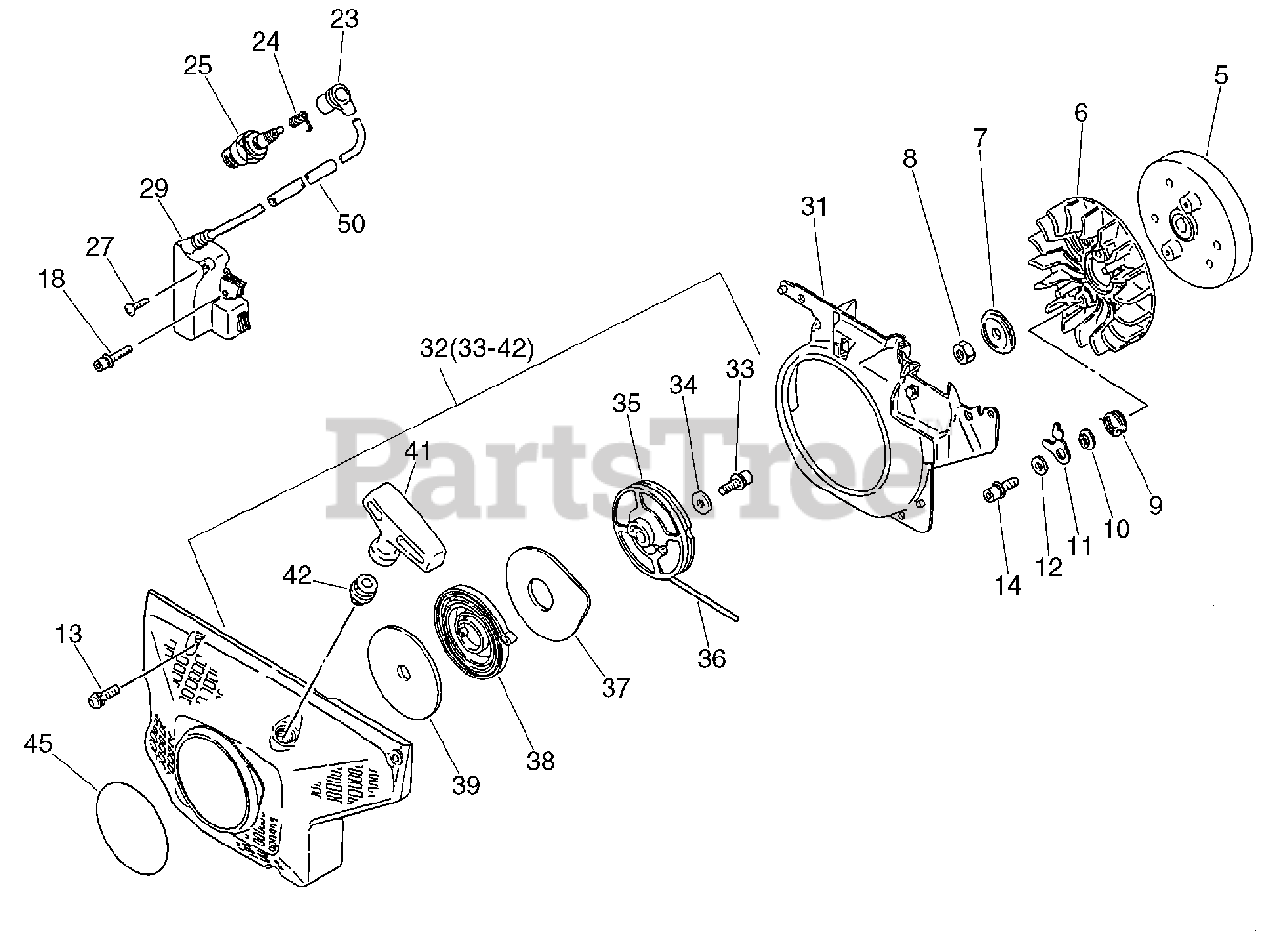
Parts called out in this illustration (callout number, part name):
5	FLYWHEEL
7	WASHER - CUP
9	SPRING, RETURN
11	PAWL, STARTER
12	WASHER - 5
13	SCREW - 5X20
14	SCREW - 5X14
18	SCREW - 4X20
23	CAP, SPARK PLUG
24	TERMINAL, SPARK PLUG CAP
25	SPARK PLUG -- RCJ-6Y
27	SCREW - 4X8
29	COIL, IGNITION
31	SHIELD, FAN
32	STARTER ASSY
33	SCREW - 5X14
34	WASHER - 5
35	REEL, ROPE
36	ROPE, STARTER - 4X950
37	PLATE, STARTER
38	SPRING, REWIND
39	PLATE, STARTER
41	GRIP, STARTER
42	GUIDE, ROPE
45	LABEL - ECHO
50	TUBE
